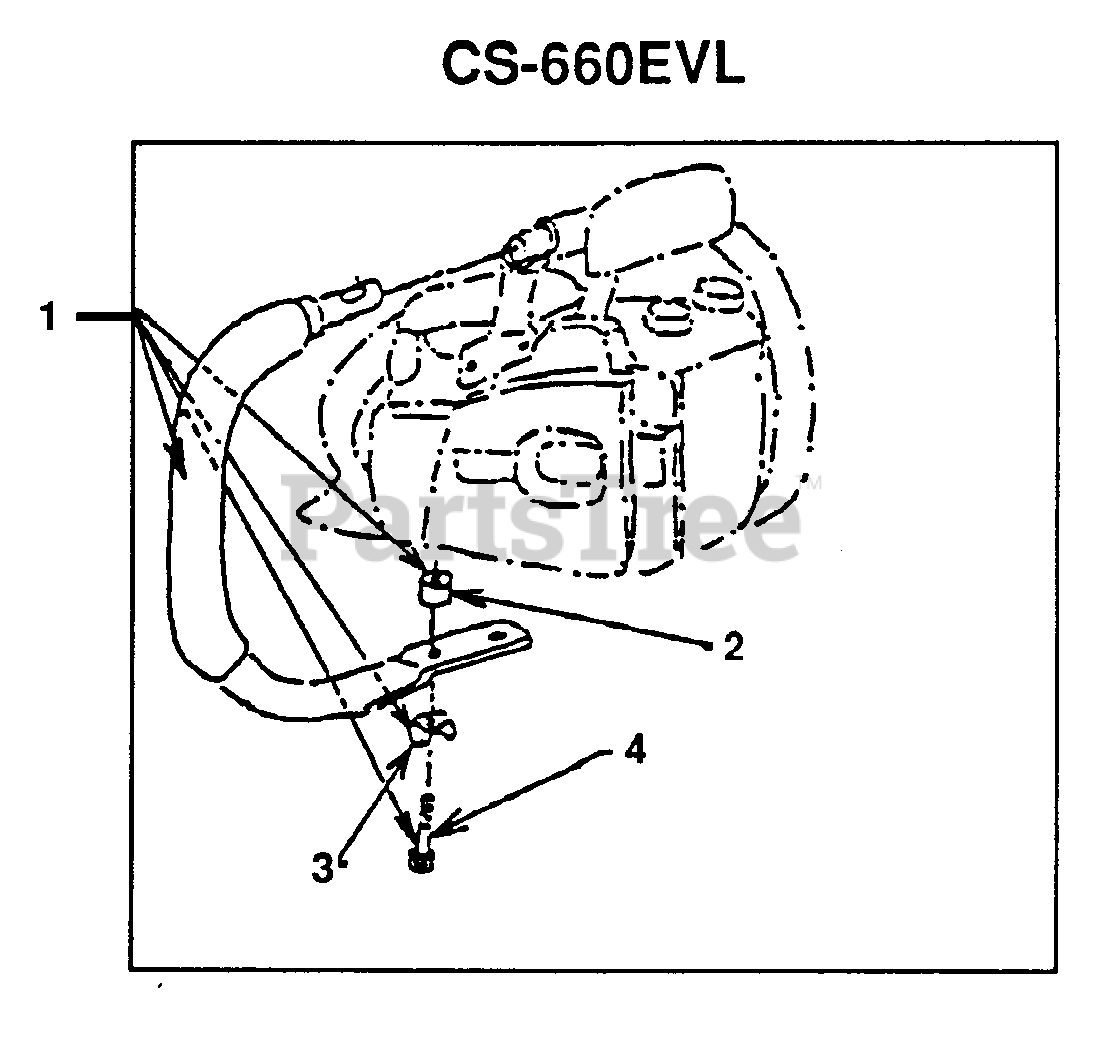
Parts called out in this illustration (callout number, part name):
1	HANDLE KIT
3	SPACER
4	SCREW - 5X40
